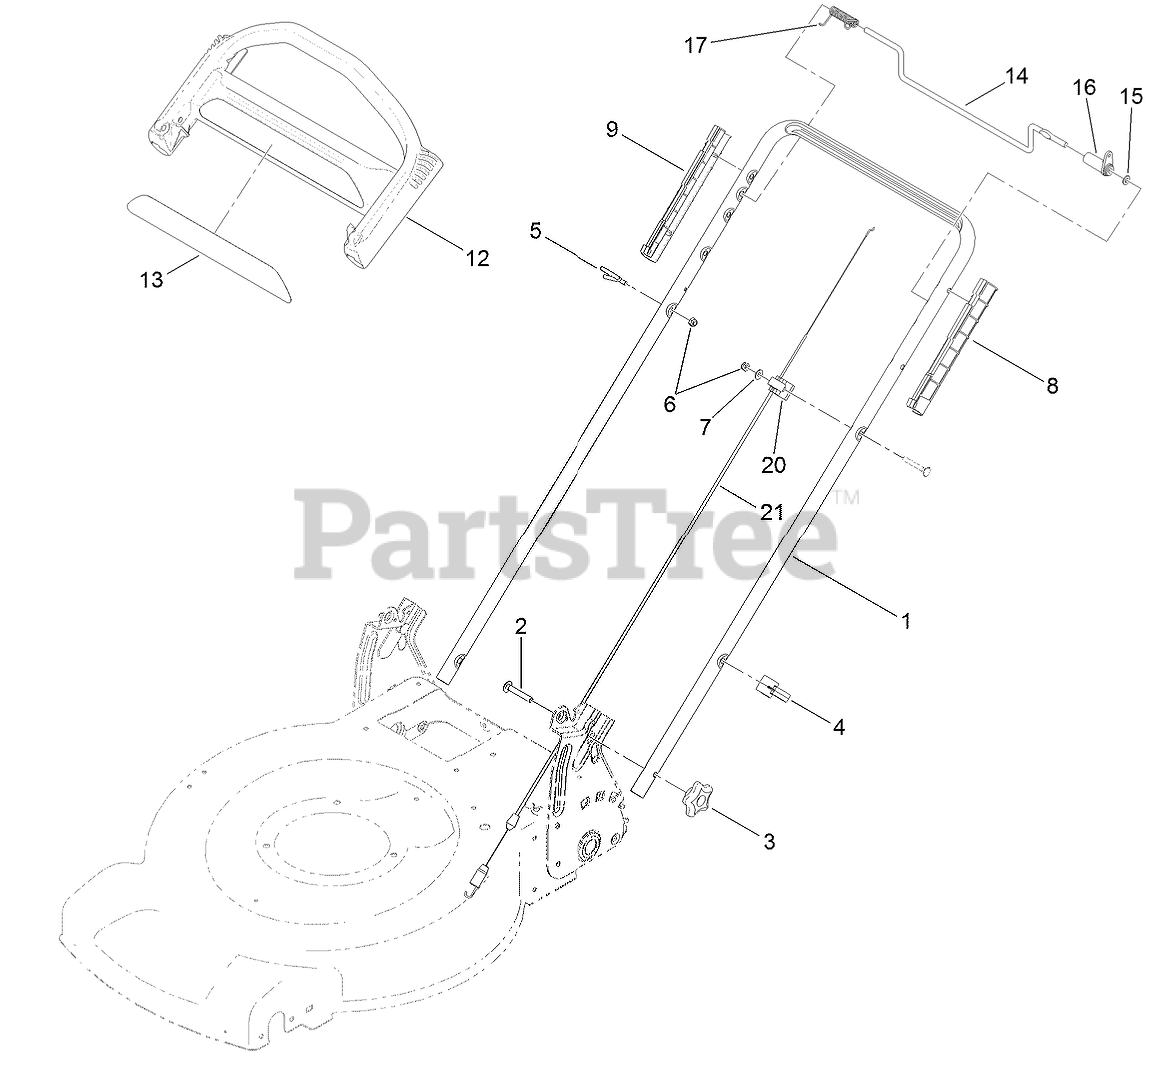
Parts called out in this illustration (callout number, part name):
2	Screw-CARR
3	KNOB-HANDLE
4	GUIDE-CABLE
5	GUIDE-ROPE
6	NUT-LOCK, NI
7	WASHER-FLAT
8	GUIDE-LH
9	GUIDE-RH
12	HANDLE-CONTROL
14	BAR-CONTROL, TRACTION
15	WASHER-PLAIN
16	LEVER-TRACTION
17	Spring-Torsion
20	ANCHOR-CABLE
21	CABLE-TRACTION
